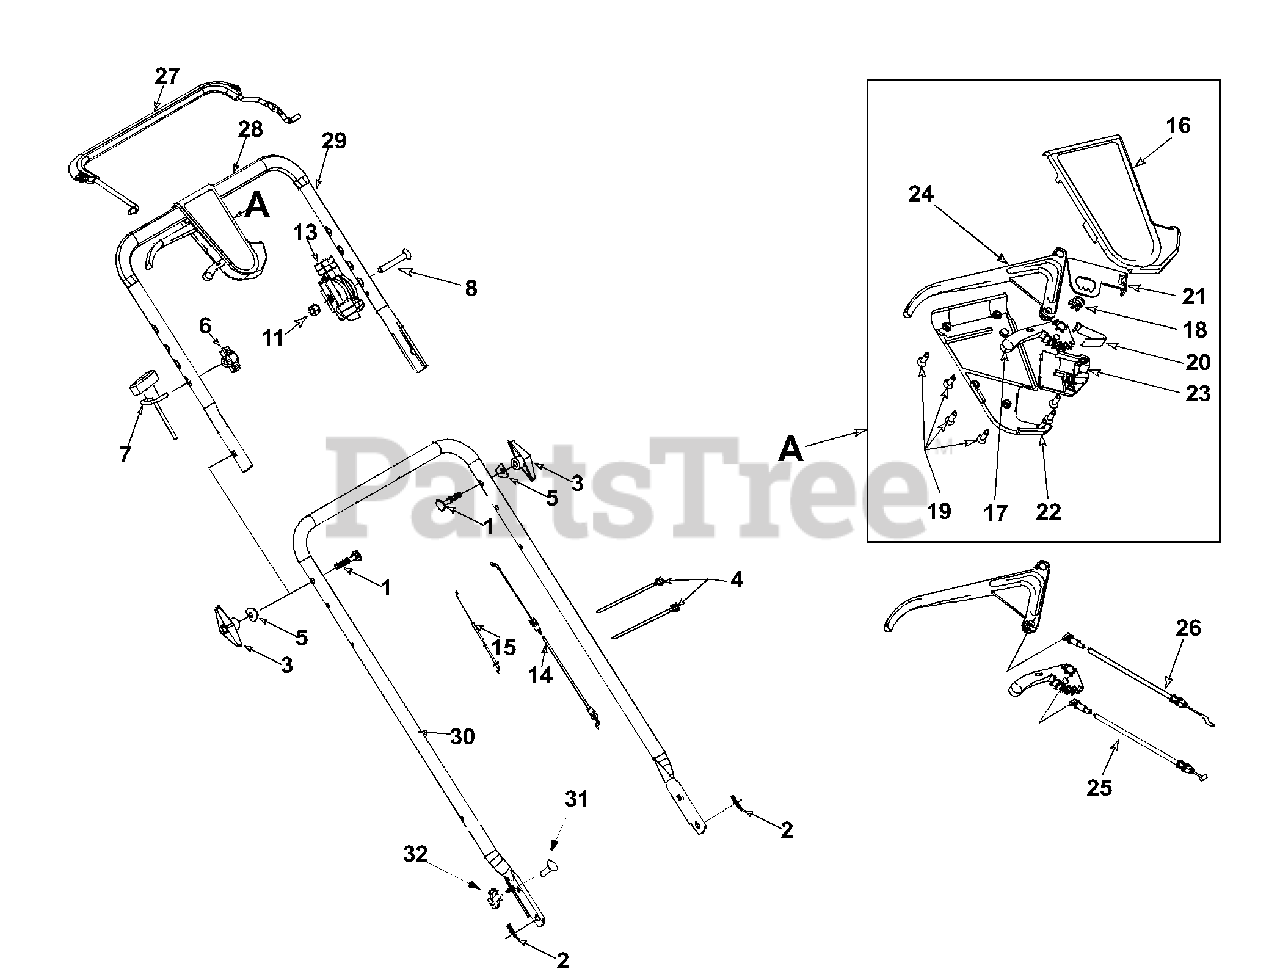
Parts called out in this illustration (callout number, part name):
1	Bolt Curv. Carr. 5/16-18 x 2.0
2	Cotter Pin .072 x 1.12 Lg.
3	Knob Assembly
4	Strap
5	Wash. Sad. .320 ID x.830 OD
6	Knob Handle ERS - 1/4-20
7	Rope Guide Eyebolt
8	Oval C-Sunk Screw
11	Nut 1/4-20 Top lock Nut Insert
13	Control Housing
14	Control Cable
16	Upper Control Housing
17	6 Speed Shift Lever
18	Gear Insert
19	CSunk Tap Scr #10 x .75 L
20	Shift Lever Spring
21	6 Spd. Rack Cable Brkt.
22	Lower Control Housing
23	Cable Mounting Cap
24	Control Lever
25	6 Speed Cable
26	Control Cable
27	Control Handle
28	Foam Grip (2 Reqd.)
31	Carriage Bolt
32	Wing Nut
